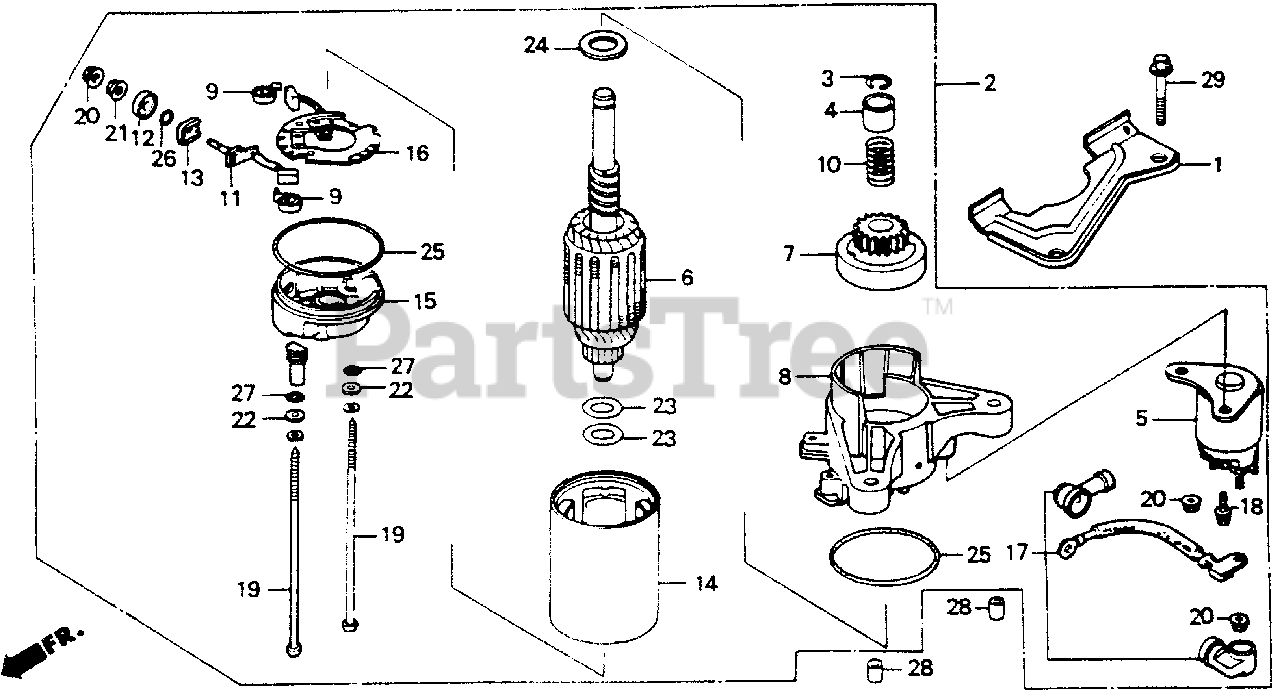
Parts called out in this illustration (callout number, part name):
1	PLATE, SIDE
2	MOTOR ASSY., STARTER
3	RING, SNAP
4	COLLAR, CLUTCH STOP
5	CONTACTOR ASSY.
7	CLUTCH ASSY., OVERRUNNING
8	HOUSING, DRIVE SIDE
9	SPRING, BRUSH
12	BUSH, INSULATION
13	BUSH, INSULATION
15	FRAME, STARTER END
16	PLATE, BRUSH HOLDER
17	WIRE, WATER COVER
18	BOLT
19	BOLT, THROUGH (NOT AVAILABLE)
22	WASHER, STEEL PLATE
23	WASHER
28	PIN, DOWEL (10X16)
29	BOLT, FLANGE (8X35)
